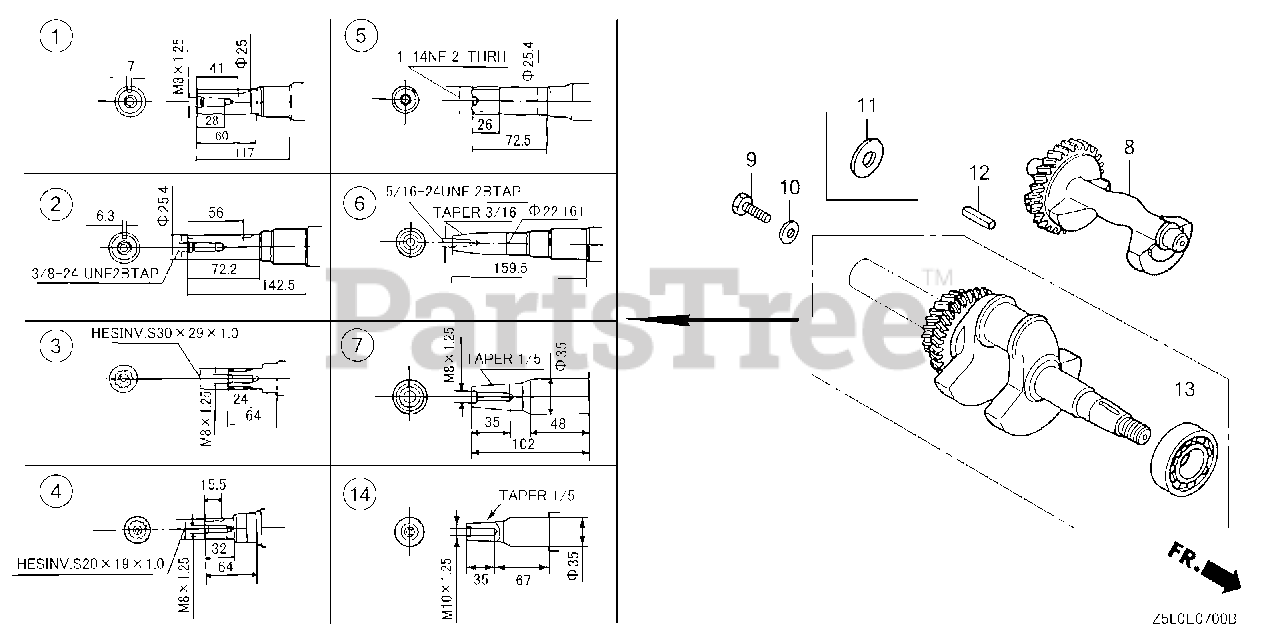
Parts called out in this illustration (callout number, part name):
5	CRANKSHAFT
8	WEIGHT, BALANCER
13	BEARING, RADIAL BALL (6207SH)
